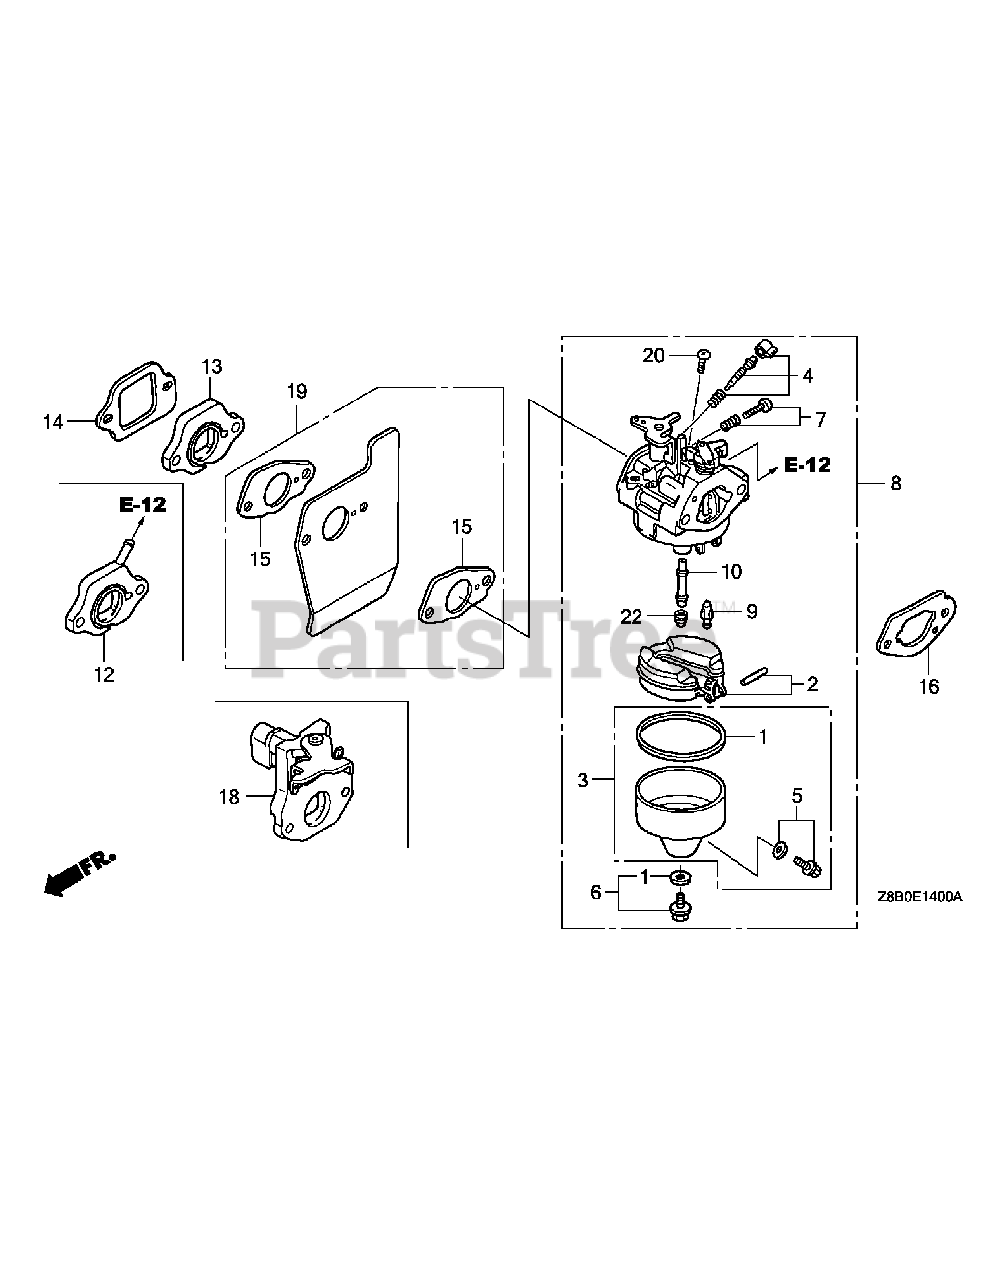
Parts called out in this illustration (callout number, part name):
1	PACKING KIT
3	CHAMBER SET, FLOAT
5	SCREW SET, DRAIN
6	SCREW SET
7	SCREW SET (THROTTLE STOP)
8	CARBURETOR ASSY. (BB62Z A)
9	VALVE, FLOAT
10	NOZZLE, MAIN
12	INSULATOR, COMP. CARBURETOR
13	INSULATOR, CARBURETOR
14	PACKING, INSULATOR
15	PACKING, CARBURETOR
16	PACKING, CARBURETOR
18	CONTROL ASSY., CHOKE
19	GUIDE COMP., AIR
20	SCREW, PAN, 5X6
22	JET, MAIN, #60
22	JET, MAIN, #62
22	JET, MAIN, #65
